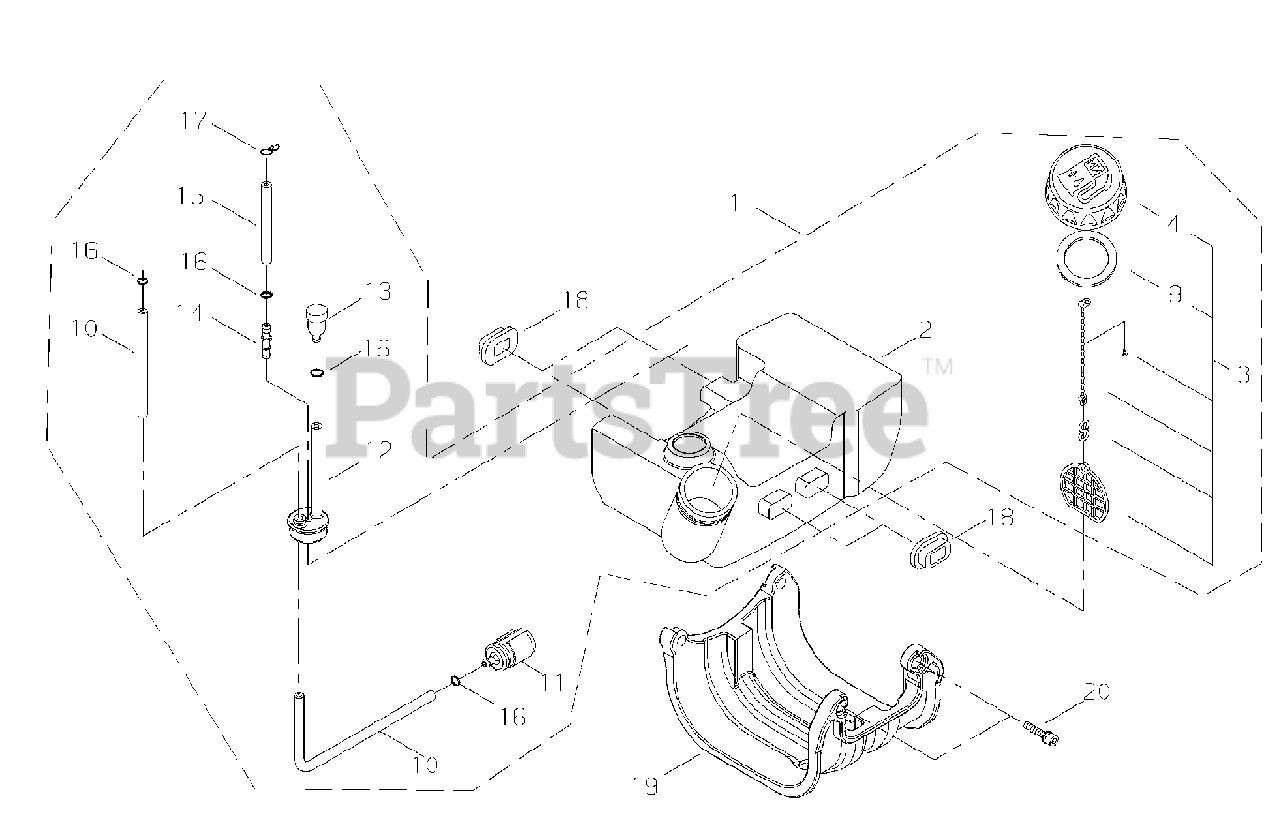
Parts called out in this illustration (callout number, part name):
2	TANK, FUEL
3	CAP ASSY
4	CAP, FUEL
9	GASKET, CAP
10	PIPE - FUEL
11	FILTER, FUEL
12	GROMMET
13	VALVE
14	CONNECTOR, PIPE
15	PIPE
16	RING, RETAINING - 6
17	CLIP - SPRING
18	CUSHION, FUEL TANK
19	GUARD, FUEL TANK
20	SCREW - 5X20
